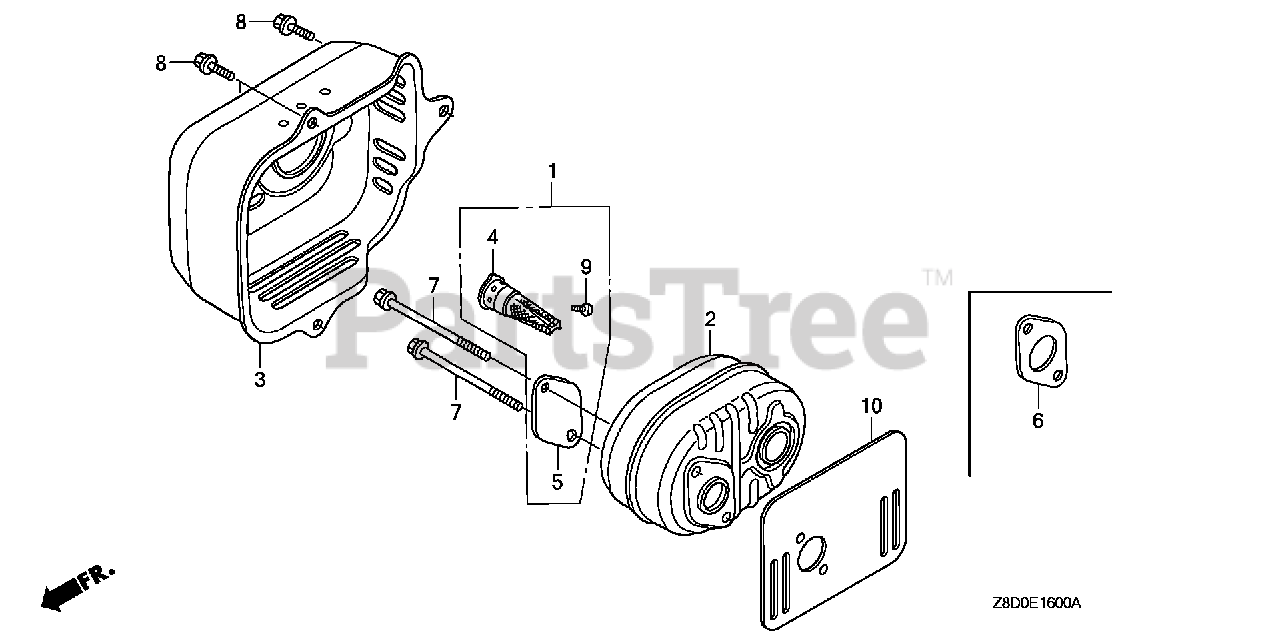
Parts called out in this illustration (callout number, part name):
1	ARRESTER KIT, SPARK
3	PROTECTOR, MUFFLER
4	ARRESTER, SPARK
5	PLATE, ARRESTER NUMBER
6	GASKET, MUFFLER
7	BOLT, FLANGE (6X79) (CT200)
8	BOLT, FLANGE (6X12) (CT200)
9	SCREW, TAPPING (4X6)
